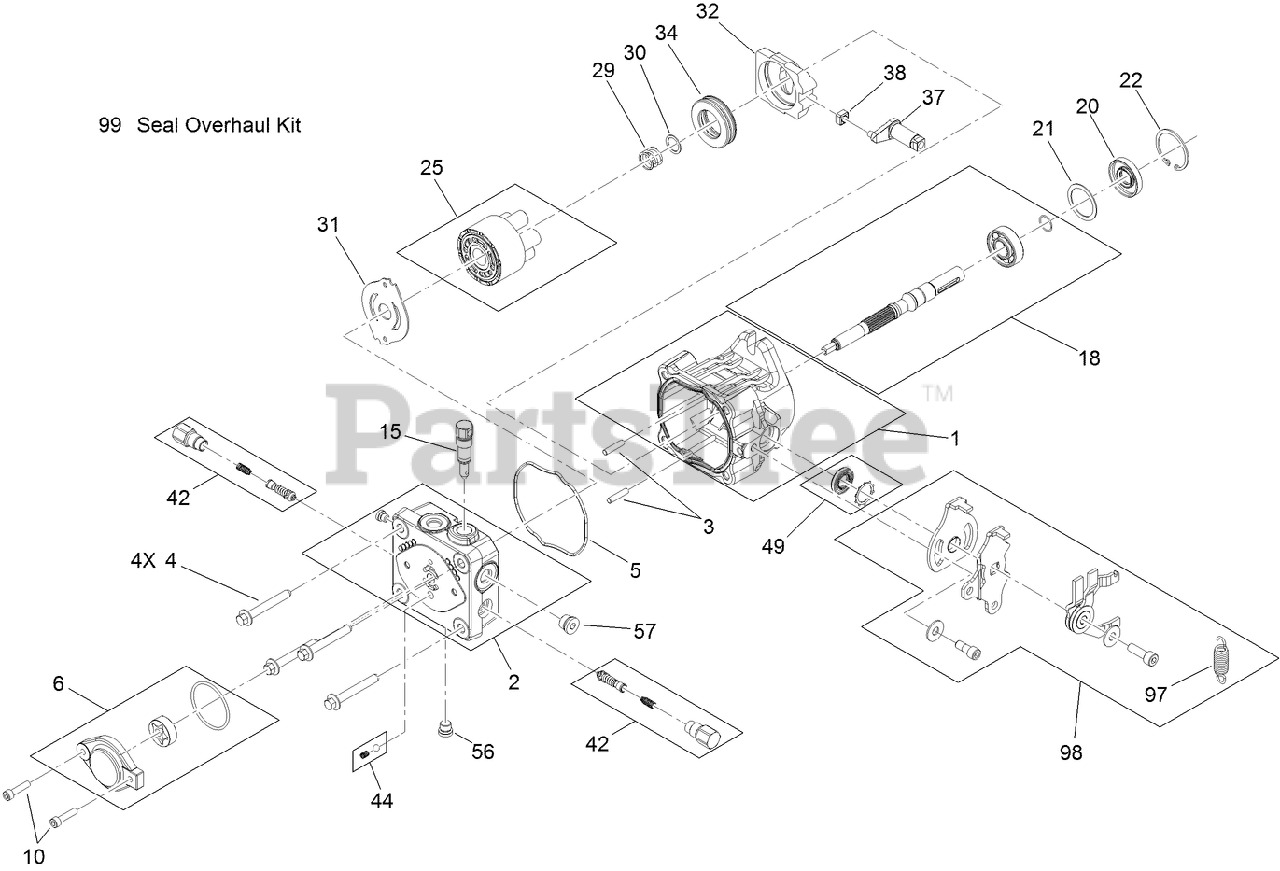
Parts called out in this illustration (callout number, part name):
1	HOUSING KIT
2	END CAP KIT (W/POPPETS)
3	PIN-HEADLESS, STRAIGHT
4	BOLT-HF
5	O-RING
6	CHARGE PUMP KIT
10	CAPSCREW
15	BYPASS VALVE KIT
18	INPUT SHAFT KIT
20	SEAL-LIP
21	SPACER
22	RING-RETAINING
25	CYLINDER BLOCK KIT
29	SPRING-BLOCK
30	WASHER-THRUST
31	Plate-Valve
32	SWASHPLATE-VARIABLE
34	BEARING-THRUST
37	ARM-TRUNNION, TAPERED SQUARE
38	GUIDE-SLOT
42	SHOCK VALVE KIT
44	CHARGE RELIEF KIT
49	TRUNNION SEAL / RETAINER KIT
56	PLUG-HSH
57	PLUG-THREAD, STRAIGHT
97	SPRING-EXTENSION
98	RETURN KIT
99	SEAL OVERHAUL KIT
